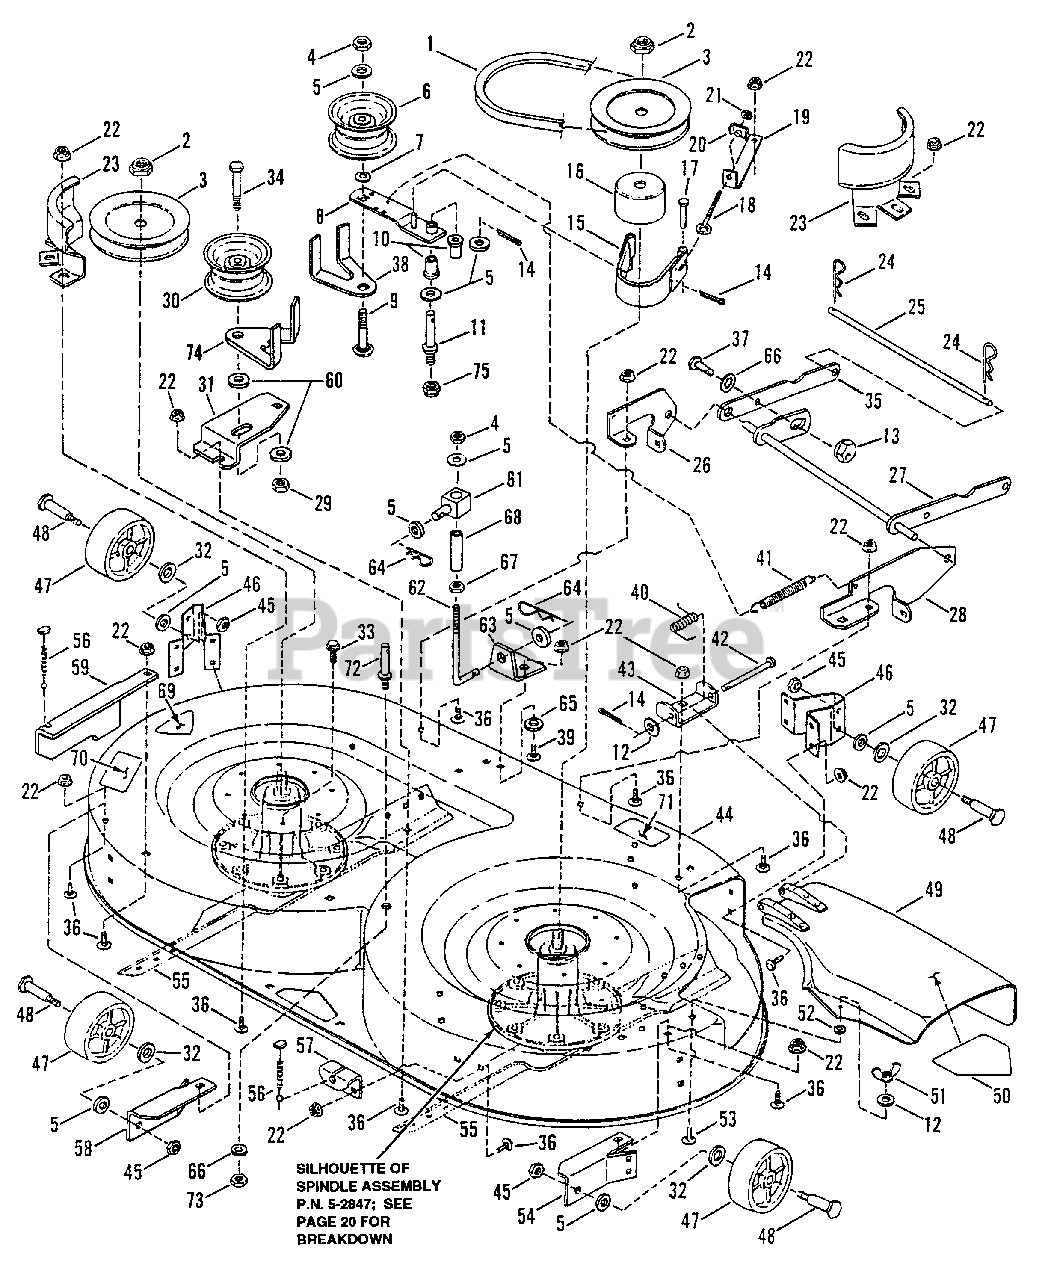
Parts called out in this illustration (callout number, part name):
1	BELT, Drive, 38" Cutting Deck
2	NUT, 5/8-18 Hex Nyloc
3	PULLEY, Spindle
4	NUT, 3/8-16 Hex Nyloc
5	WASHER, 3/8" Flat
6	PULLEY, Idler
7	RETAINER, 3/8 Bolt
8	ARM, Idler Pulley
9	BOLT, 3/8-16 x 2 3/4" Short Neck Carriage, Grade 5
10	BUSHING, Flange
11	STUD, Idler
12	WASHER, Flat
13	ECCENTRIC, Leveling
14	COTTER-PIN, 3/32 x 3/4"
15	ASSEMBLY, Brake Band
16	DRUM, Brake
17	PIN, 1/4 x 1 5/8" Clevis
18	BOLT, 1/4-20 Eye
19	ANCHOR, Blade Brake
20	NUT, 1/4-20 "T" Lock
21	NUT, 1/4-20 Hex
22	NUT, 5/16-18 Hex Flange Lock
23	GUARD, Belt
24	PIN, Hair
25	PIN, Deck Hanger
26	BRACKET, Front Lift Arm (Left Side)
27	LIFT, Front Arm
28	BRACKET, Front Lift Arm (Right Side)
29	NUT, 1/2-13 Hex Nyloc
30	PULLEY, Idler
31	BRACKET, Idler
32	WASHER, 1/2 Flat
33	SCREW, 3/8-16 x 3/4" Self-Tapping
34	BOLT, 1/2-13 x 3" Hex Head Cap
35	ARM, Front Lift
36	BOLT, 5/16-18 x 5/8" Short Neck Carriage
37	SCREW, 3/8-24 x 1 1/4" Hex Head Cap, Grade 2
38	GUIDE, Belt
39	BOLT, 5/16-18 x 3/4" Short Neck Carriage
40	SPRING, Chute Deflector Hinge
41	SPRING, Blade Brake
42	PIN, 5/16 X 3 3/16" Clevis
43	HINGE, Chute Deflector
44	DECK, 38" Cutting
45	NUT, 3/8-24 Hex Lock
46	BRACKET, Gage Wheel, Front
47	WHEEL, Gage
48	BOLT, 3/8-24 Shoulder
49	ASSEMBLY, Chute Deflector
50	DECAL, Danger
51	NUT, 5/16-18 Wing
52	RETAINER, 5/16 Bolt
53	BOLT, 5/16-18 x 3/4" Short Neck Carriage, Grade 2
54	BRACKET, Wheel (Right Side)
55	BLADE, 19-1/2"
56	CABLE, Rear Lift
57	BRACKET, Rear Deck Lift (Right Side)
58	BRACKET, Wheel (Left Side)
59	BRACKET, Rear Deck Lift (Left Side)
60	WASHER, .406 I.D. x 1.50 O.D. x .20
61	SWIVEL, Lift
62	BOLT, "J"
63	BRACKET, Angle (Front)
64	PIN, Hair
65	WASHER, 7/16 Flat
66	WASHER, 3/8 Internal Tooth Lock
67	NUT, 3/8-16 Hex
68	SPACER, Lift
69	DECAL - 38 Inch
70	DECAL - CAUTION (Rotating Blades)
71	DECAL - CAUTION
72	STOP, Deck
73	NUT, 3/8-24 Hex
74	GUIDE, Belt
75	NUT, 5/16-24 Hex Lock
